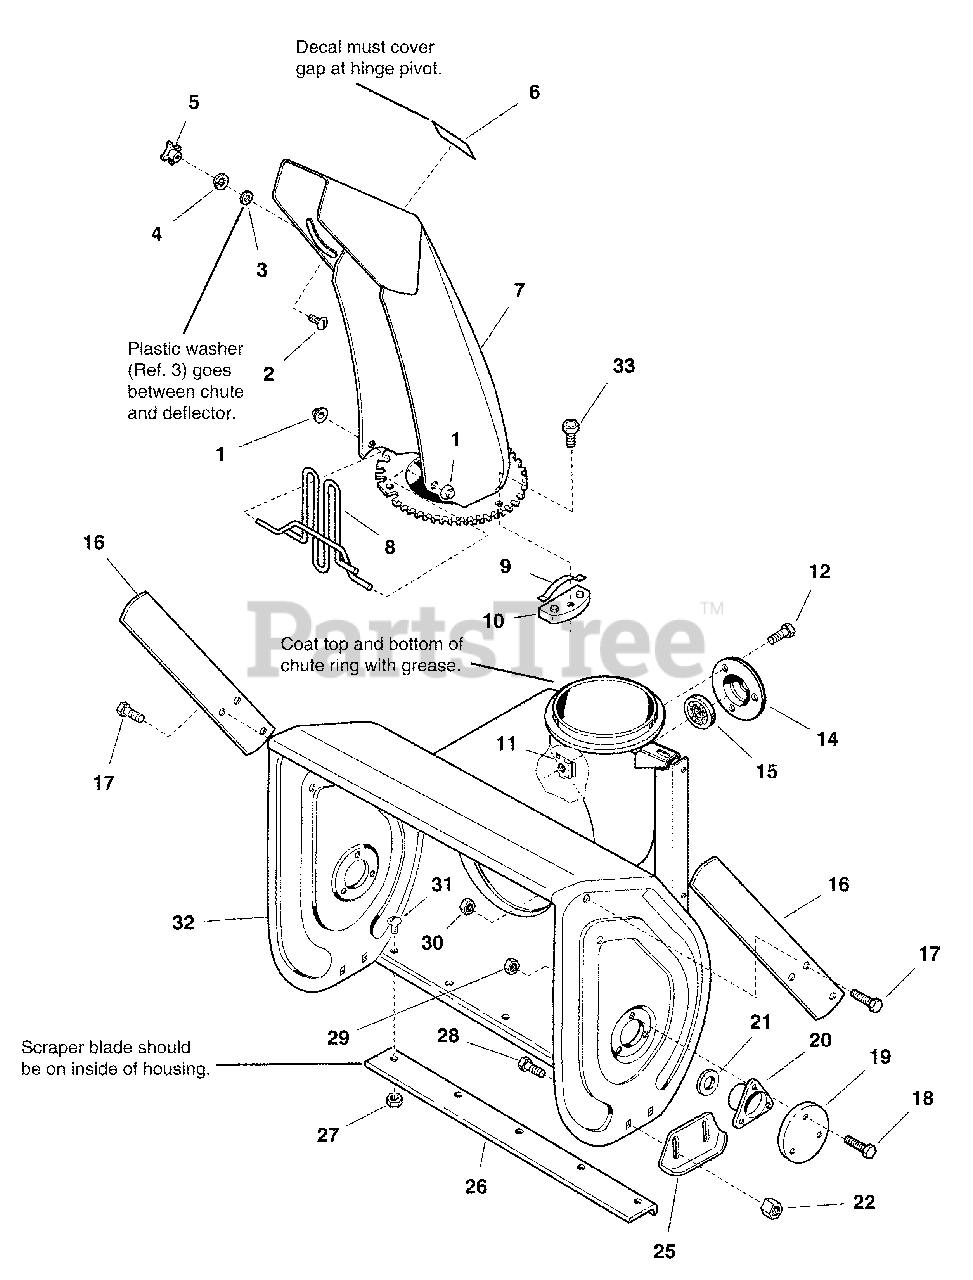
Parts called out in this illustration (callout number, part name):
1	PUSH NUT, 1/4
2	CARRIAGE BOLT, 5/16-18 x 3/4
3	WASHER, Nylon
4	WASHER, Flat, 11/32
5	KNOB, w/5/16-18 Threaded Insert
6	SEAL, Hinge Decal
7	CHUTE & DEFLECTOR ASSEMBLY
8	GUARD & SUPPORT ASSEMBLY, Chute
10	HOLD DOWN, Chute, Black Nylon
11	NUT, Retainer, 5/16-18
12	CAPSCREW, Hex Head, 5/16-18 x 17/64
14	RETAINER, Bearing
15	BEARING, Ball
16	CUTTER, Drift, (Optional)
17	CAPSCREW, Hex Head, 5/16-18 x 3/4, (Optional)
18	CAPSCREW, Hex Head, 5/16-18 x 7/8
19	BEARING, Cap
20	BEARING, Auger, Flange
22	NUT, ESNA Flange 3/8-16
26	BLADE, Scraper, 24"
27	NUT, Hex Flange, 2-Way Lock, 5/16-18
28	CARRIAGE BOLT, Round Head Square Neck 3/8-16 x 3/4
29	NUT, Hex, Center Lock, 5/16-18
30	NUT, Hex, 5/16-18 Conical Washer
31	CARRIAGE BOLT, Round Head Square Neck 5/16-18 x 5/8
32	HOUSING ASSEMBLY, Auger, 24"
33	CAPSCREW, Hex Head, Plastite, 10-14 x 5/8
